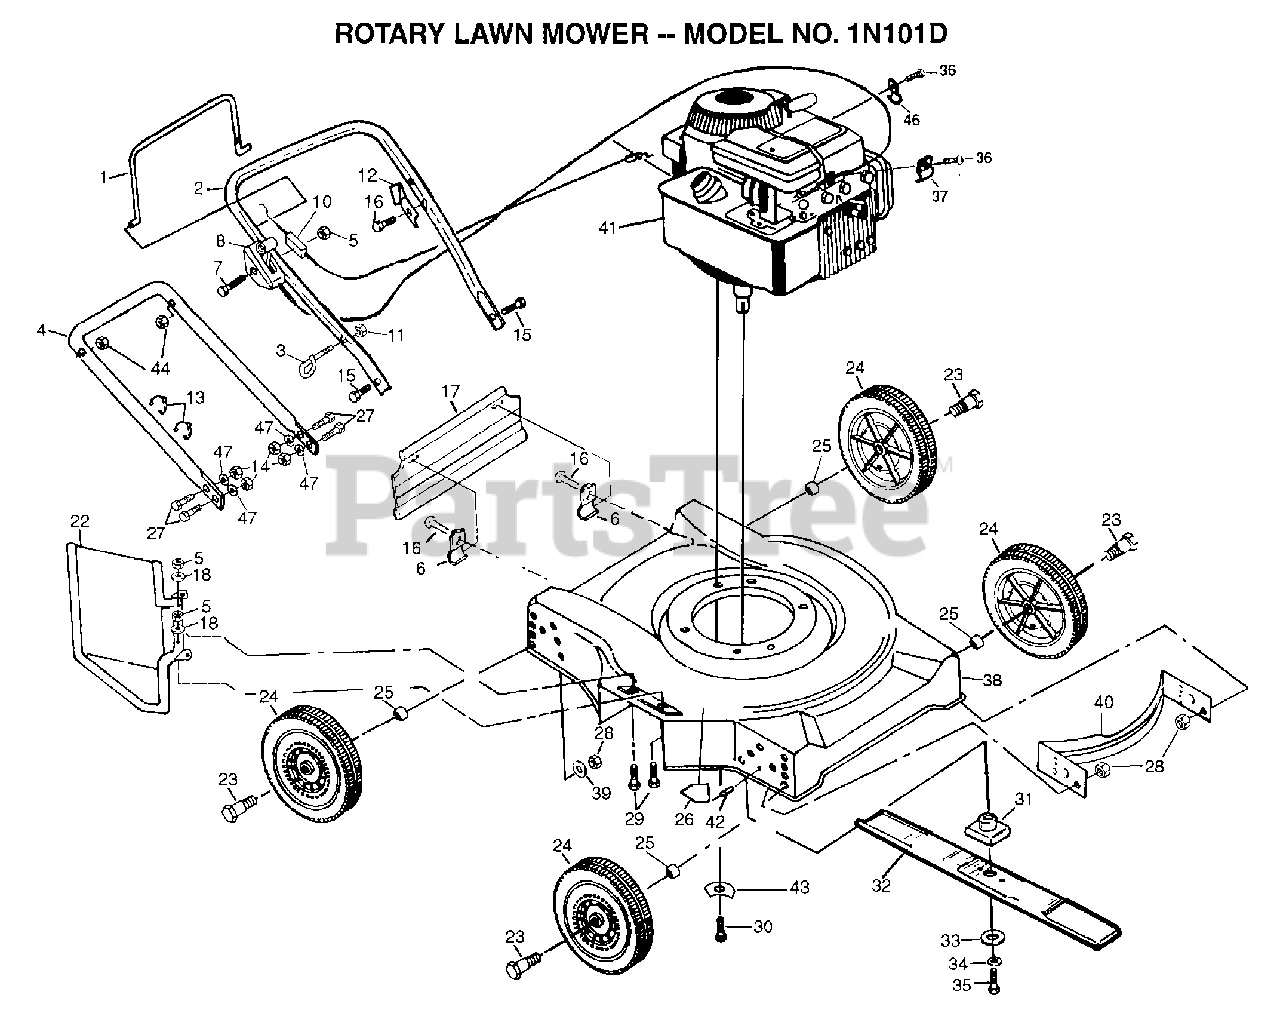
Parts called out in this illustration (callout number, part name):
1	CONTROL BAR PM
2	UPPER HANDLE
3	ROPE GUIDE
4	HANDLE LWR PM
6	"BRKT,DEFL PM"
7	SCREW.HXHD.WASH.
10	CABLE.CONT.ENG
12	"BRKT,UPSTOP"
14	LOCKNUT
15	BOLT 1/4-20-1 1/2
16	TAPPING SCREW
17	SKIRT.REAR.20RD.
22	"GRD,DISCHARGE"
23	AXLE BOLT
24	WHEEL ASSY
26	DECAL HYT
28	LOCKNUT PM
29	BOLT LT
30	BOLT.ENG.3/8-16
31	BLADE ADAPTOR
32	BLADE.20.MULCH.AY
33	"WASHER,HARDEN"
34	LOCKWASHER
35	SCREW
36	SCREW PM
37	CABLE CLAMP
42	BLIND RIVET
46	GUIDE CLIP PM
47	STEEL WASHER
